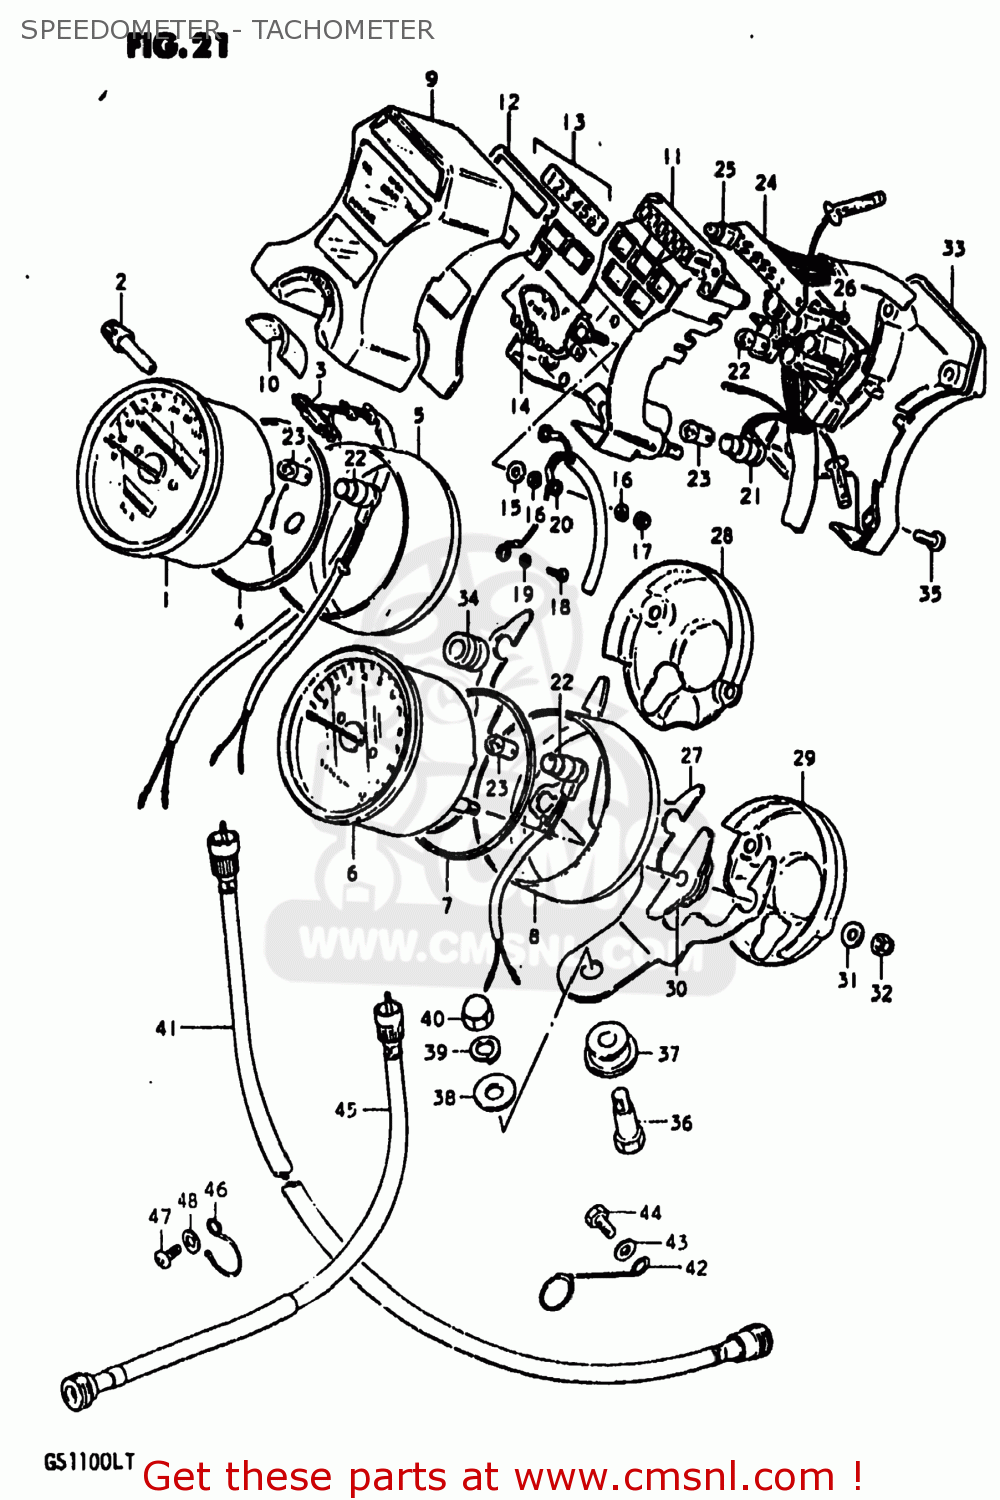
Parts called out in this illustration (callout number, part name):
1	METER,SPEEDOMETER
2	KNOB
3	WIRE,LEAD SWITCH
4	CUSHION
5	COVER,SPEEDOMETER
6	TACHOMETER
7	CUSHION
8	COVER,TACHOMETER
9	CASE,PILOT BOX,OUTER
10	SEAL,IGNITION SWITCH
11	CASE, PILOT BOX INNER
12	PLATE,PILOT BOX
13	LENS SET,PILOT
14	METER,FUEL
15	WASHER
16	LOCK WASHER
17	NUT
18	SCREW
19	LOCK WASHER
20	LEAD WIRE, FUELMETER
21	SOCKET
22	SOCKET,METER
23	BULB(12V3.4W,STANLEY,A72A)
24	SOCKET,GEAR INDICATOR
25	BULB(14V1.12W)
26	SCREW
27	BRACKET,COMBINATION METER
28	ORNAMENT,SPEEDOMETER
29	COVER,TACHOMETER
30	CUSHION,METER
31	WASHER
32	NUT
33	COVER,PILOT BOX,UNDER
34	CUSHION,PILOT BOX
35	SCREW,PILOT BOX
36	BOLT(8X31)
37	CUSHION,METER
38	WASHER(8.5X23X1.2)
39	LOCK WASHER
40	NUT
41	CABLE ASSEMBLY,SPEEDOMETER
42	GUIDE,SPEEDOMETER CABLE
43	WASHER
44	BOLT, UPPER
45	CABLE ASSEMBLY,TACHOMETER
46	GUIDE,WIRING HARNESS
47	SCREW 6X12
48	WASHER
